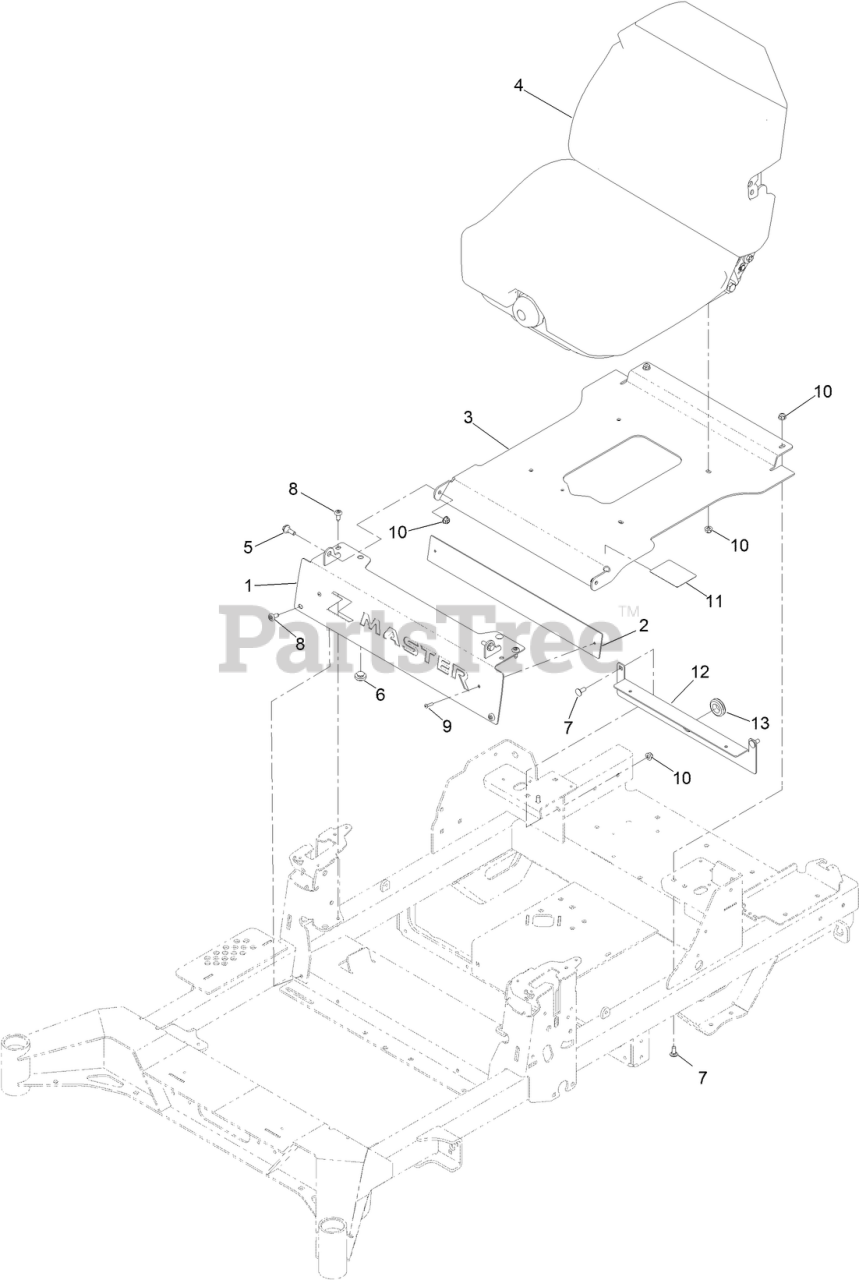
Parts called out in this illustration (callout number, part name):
1	BADGE PLATE ASM [BLACK]
2	PLATE-BACKER
3	PAN-SEAT
4	SEAT ASM-SUSPENSION
5	SCREW-SHOULDER
6	BUMPER-SEAT
7	SCREW-CARR
9	RIVET-TRIFOLD
10	NUT-HF, NI
11	DECAL-SERVICE AID
12	BRACKET-FIREWALL
13	GROMMET
